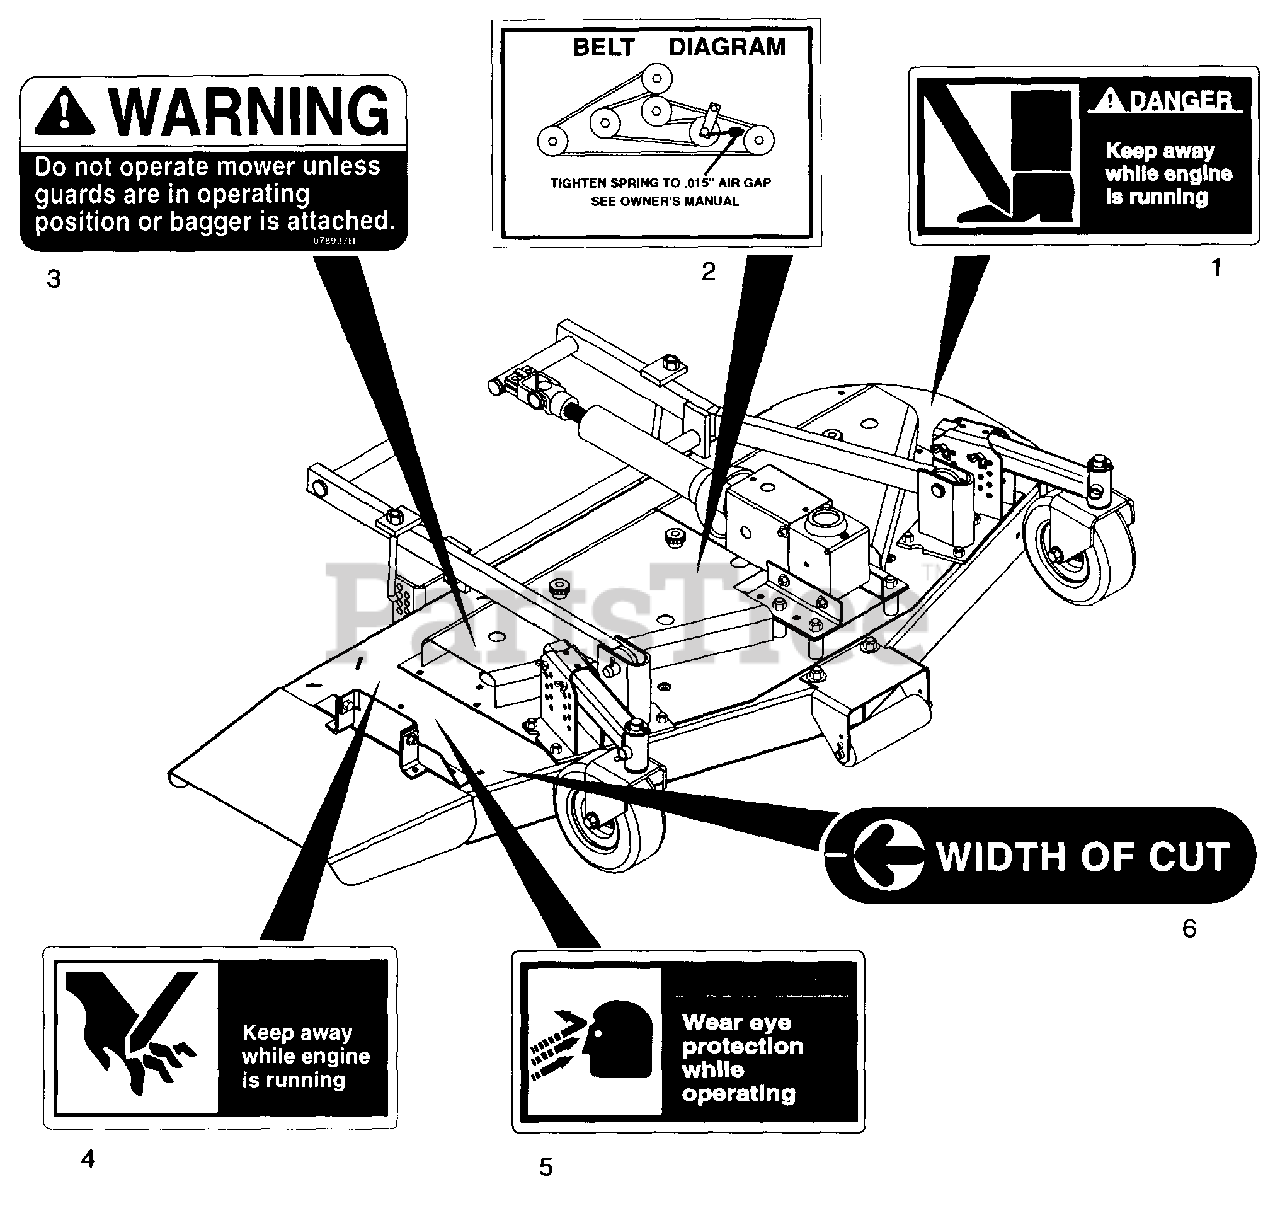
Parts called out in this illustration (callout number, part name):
1	Decal,Danger Foot
2	Decal,Belt Diagram
3	Decal, Warning
4	Decal,Danger Hand
5	Decal,Warning Eye
6	Width of Cut Decal
